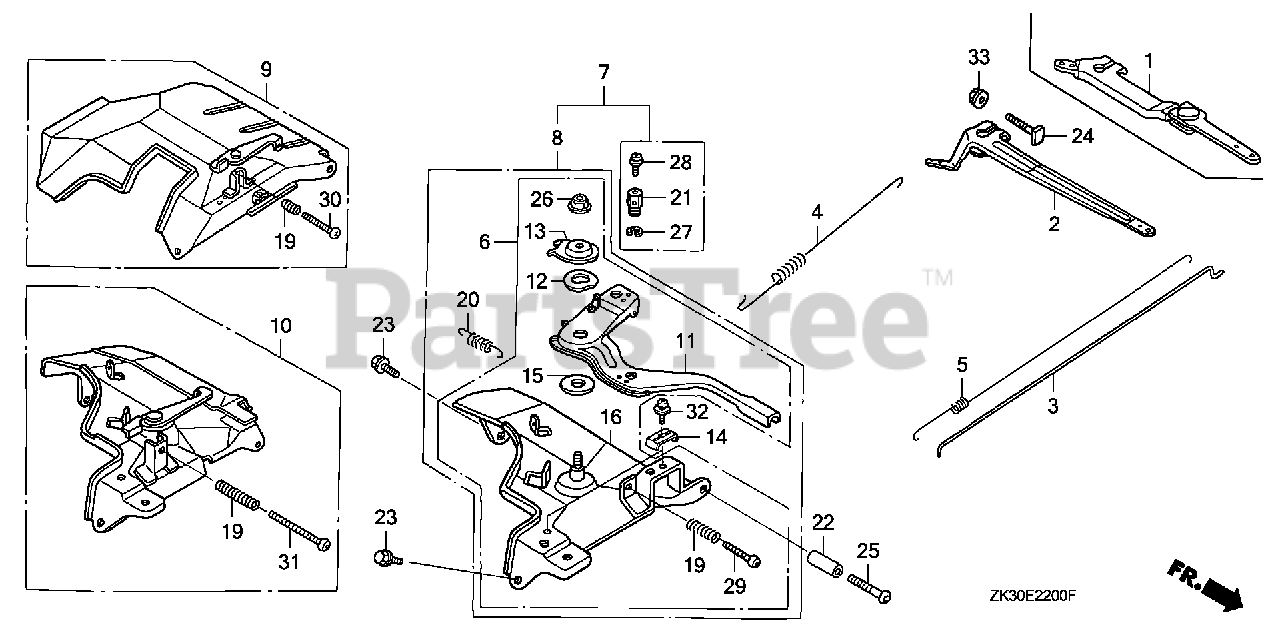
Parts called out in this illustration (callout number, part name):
2	ARM, GOVERNOR
3	ROD, GOVERNOR
4	SPRING, GOVERNOR (L=137.5MM)
5	SPRING, THROTTLE RETURN
8	CONTROL ASSY. (REMOTE)
11	LEVER, CONTROL
12	SPRING, LEVER
13	WASHER, CONTROL LEVER
14	HOLDER, CABLE
15	SPACER, CONTROL LEVER
16	BASE, CONTROL
19	SPRING, CONTROL ADJUSTING
20	SPRING, CABLE RETURN
23	BOLT, FLANGE (6X12) (CT200)
24	BOLT, GOVERNOR ARM
26	NUT, SELF-LOCK (6MM)
29	SCREW, PAN (5X32)
32	SCREW, PAN (5X16)
33	NUT, FLANGE (6MM)
